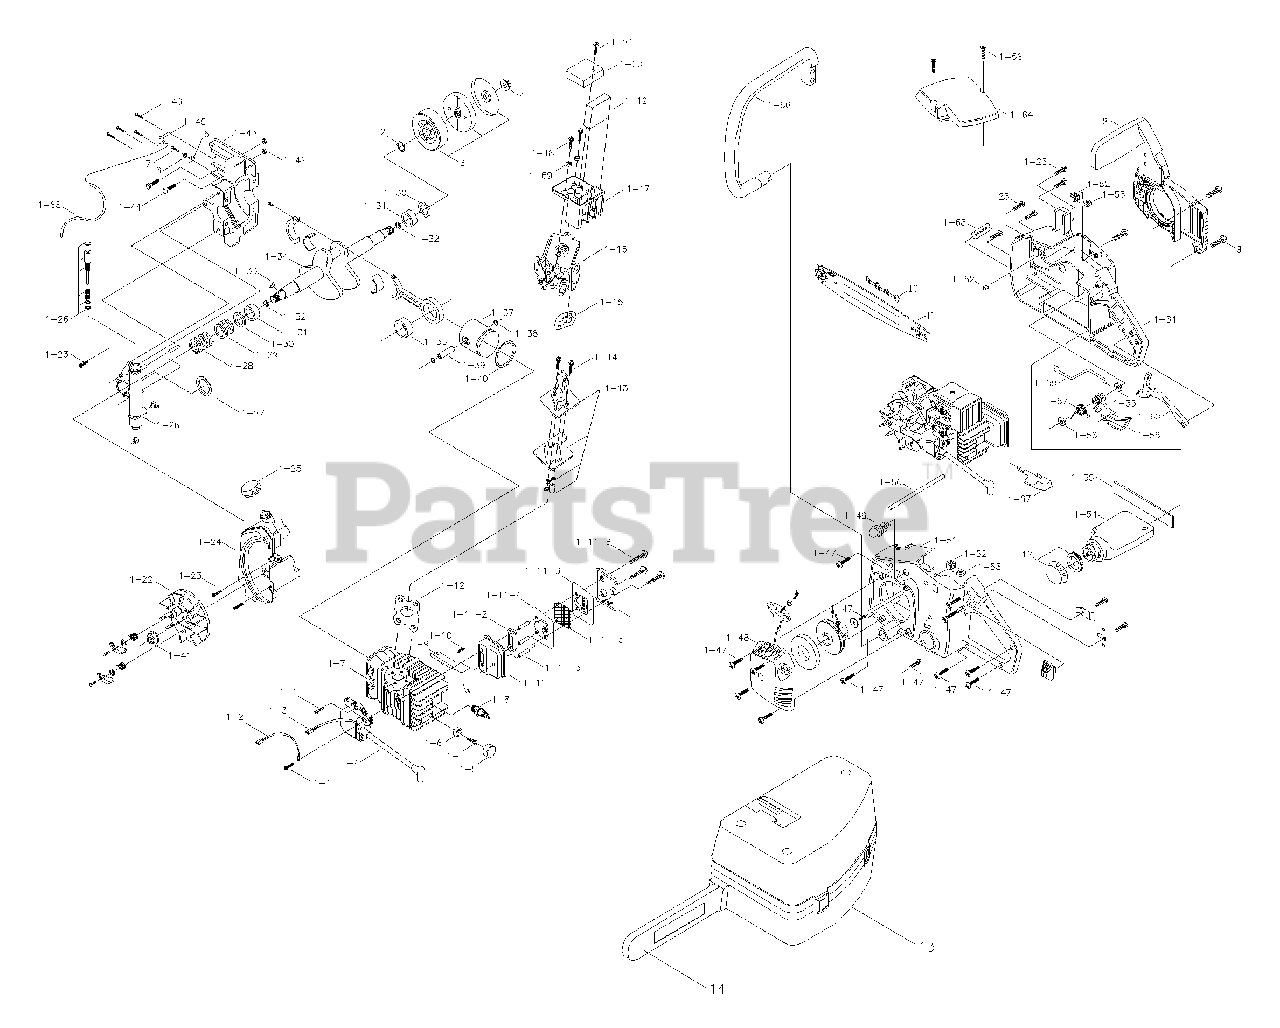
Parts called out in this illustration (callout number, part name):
1	ENGINE ASS'Y
1-2	WIRE, GROUND
1-3	WIRE, STOP SWITCH
1-4	IGNITION ASS'Y
1-5	COVER, CYLINDER
1-6	COVER, SPACER
1-9	BAFFLE, AIR
1-11	MUFFLER ASS'Y
1-11-1	COVER, MUFFLER
1-11-2	PLATE, REINFORCING
1-11-3	SPACER, MUFFLER
1-11-4	BAFFLE, OUTER
1-11-5	BAFFLER, INNER MUFFLER
1-11-6	SCREEN, SPARK ARRESTER
1-11-7	COVER, MUFFLER
1-12	GASKET, INSULATOR
1-13	INSULATOR ASS'Y
1-16	CARBURETOR
1-17	BOX, AIR FILTER
1-18	SCREW
1-19	FILTER, AIR
1-20	SHIELD, CARBURETOR
1-22	FLYWHEEL ASS'Y
1-24	FUEL TANK ASS'Y
1-25	CAP, FUEL ASS'Y
1-26	OIL PUMP ASS'U
1-29	WORM GEAR
1-30	SEAL, C'SHAFT OIL
1-33	KEY, FLYWHEEL
1-34	CRANKSHAFT ASS'Y
1-37	PISTON
1-40	PISTON RING
1-44	SCREW, BAR
1-46	SCREW
1-48	STARTER HOUSING ASS'Y
1-51	ENGINE HOUSING
1-52	RETAINER, NUT
1-54	OIL TANK ASS'Y
1-55	SPACER, OIL TANK
1-58	TRIGGER, THROTTLE
1-59	ROD, THROTTLE
1-60	LATCH, THROTTLE
1-61	HOUSING, RIGHT
1-62	FILTER, FOAM
1-64	COVER, AIR FILTER
1-67	SLIDE, CHOKE
3	DRUM ASS'Y
6	RING, RETAINING
8	BRAKE KIT ASS'Y
12	OIL CAP ASS'Y
13	CARRY CASE
